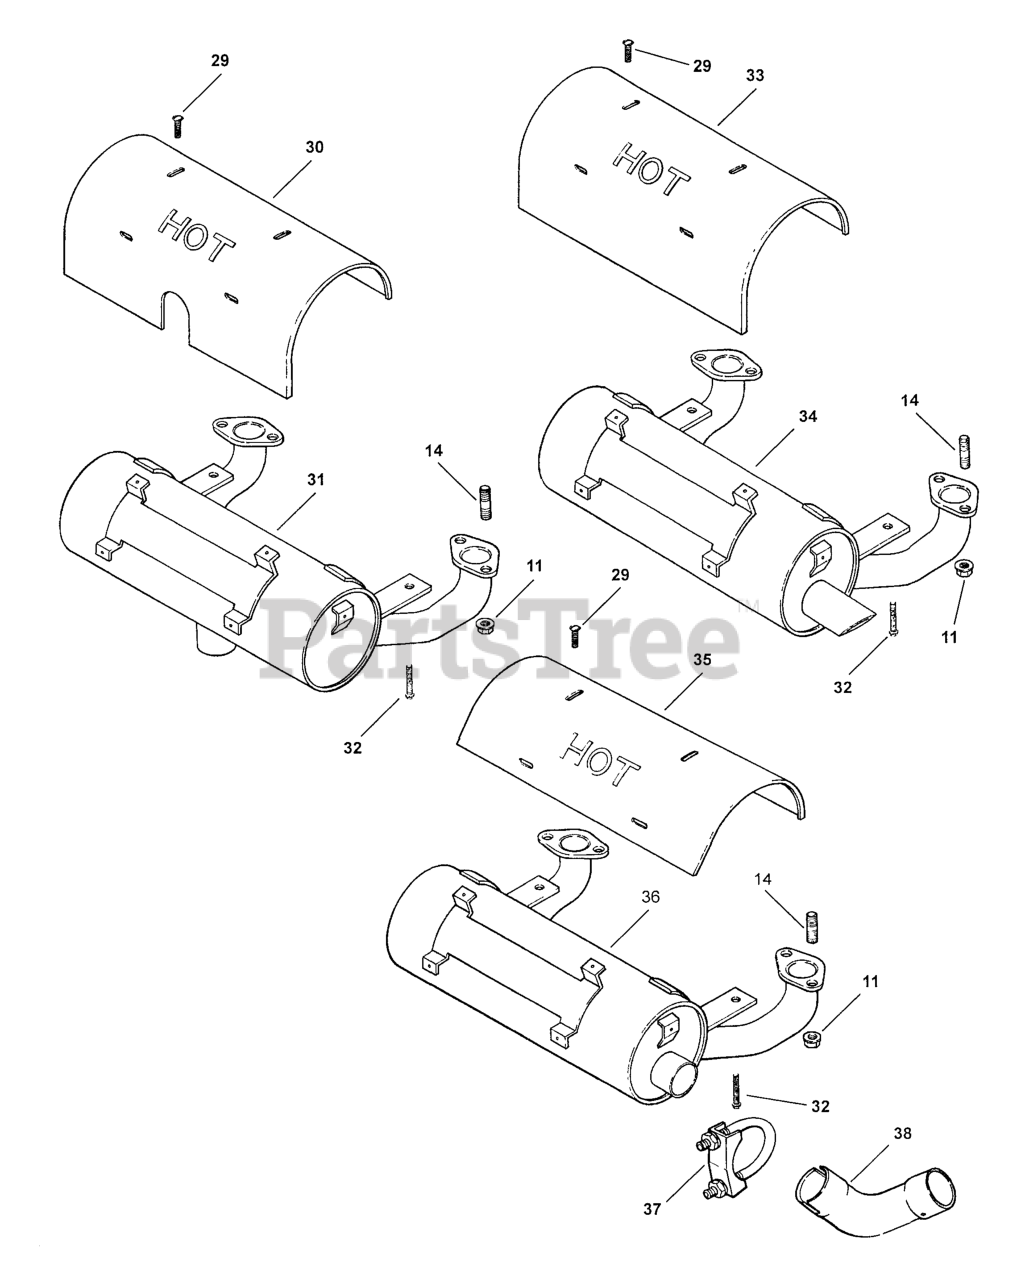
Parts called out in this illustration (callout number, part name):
11	NUT - USE M-841080
14	STUD - USE M-829033
32	SCREW - USE M-645020
36	MUFFLER, OIL FILT. SIDE USE 24 068 08-S
37	CLAMP, MUFFLER-USE 24 237 13-S
38	ELBOW, EXHAUST
